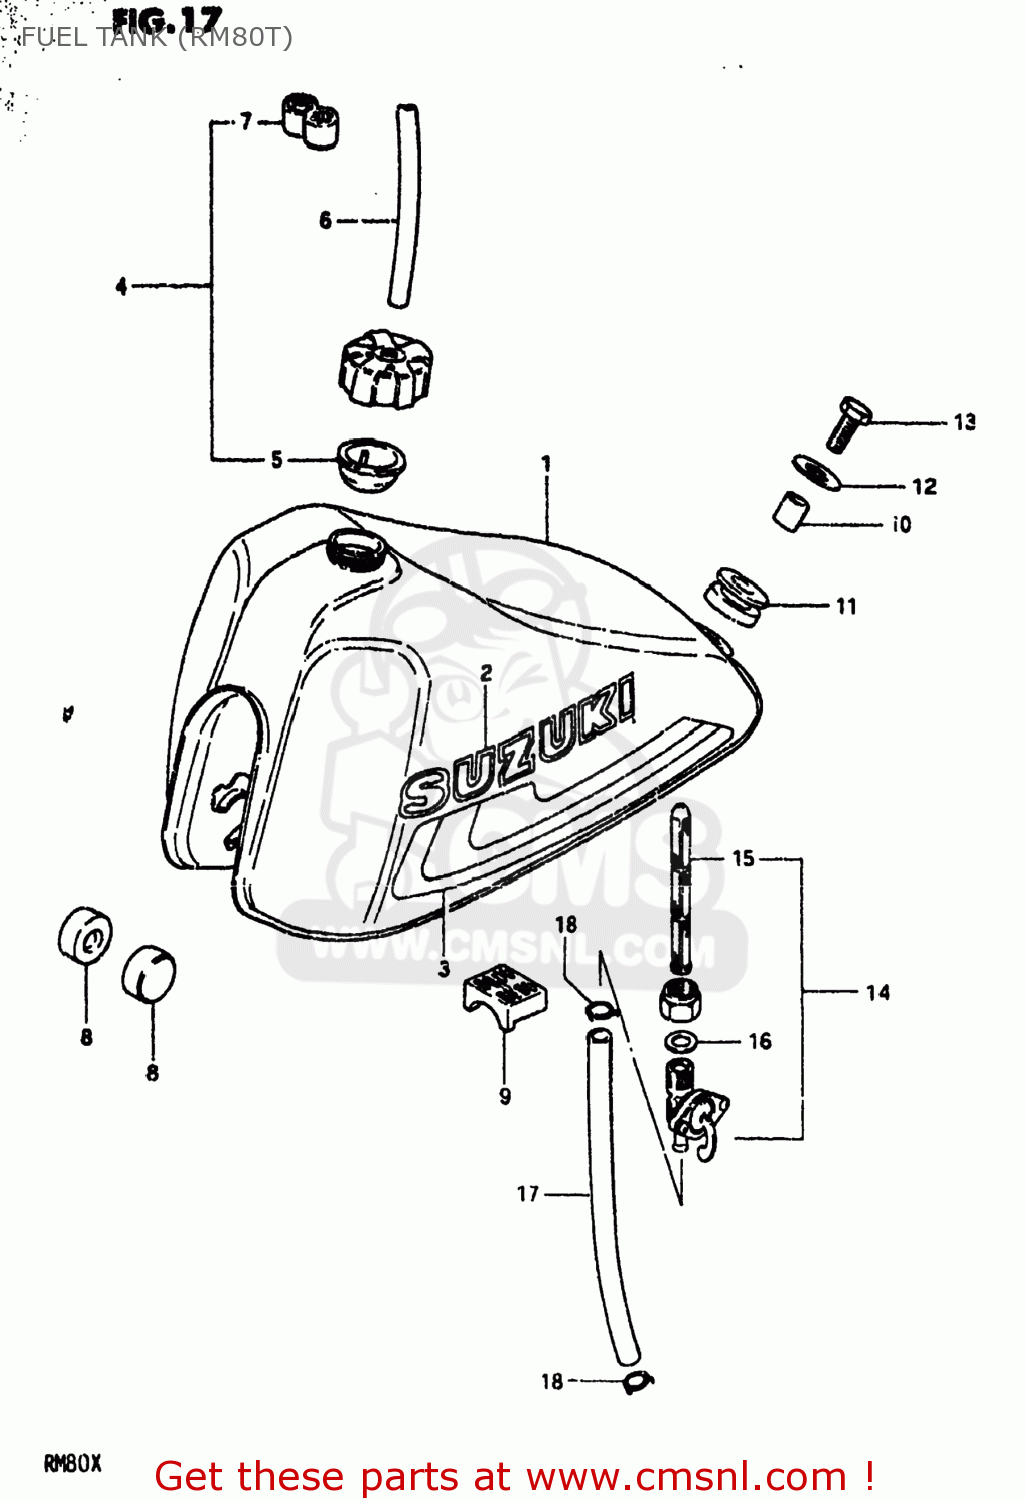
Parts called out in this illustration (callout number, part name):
1	TANK ASSEMBLY,FUEL
2	EMBLEM
3	TAPE SET,FUEL TANK
4	CAP ASSEMBLY,FUEL TANK
5	GASKET,FUEL TANK CAP
6	HOSE
7	CLAMP,FUEL TANK BREATHER HOSE
8	CUSHION
9	CUSHION,FUEL TANK
10	SPACER (8.2X12X17)
11	CUSHION
12	WASHER (8.5X29X1.6)
13	BOLT (8X30)
14	COCK ASSY,FUEL
15	FILTER,FUEL
16	GASKET,FUEL COCK (NAS)
17	HOSE
18	CLIP
